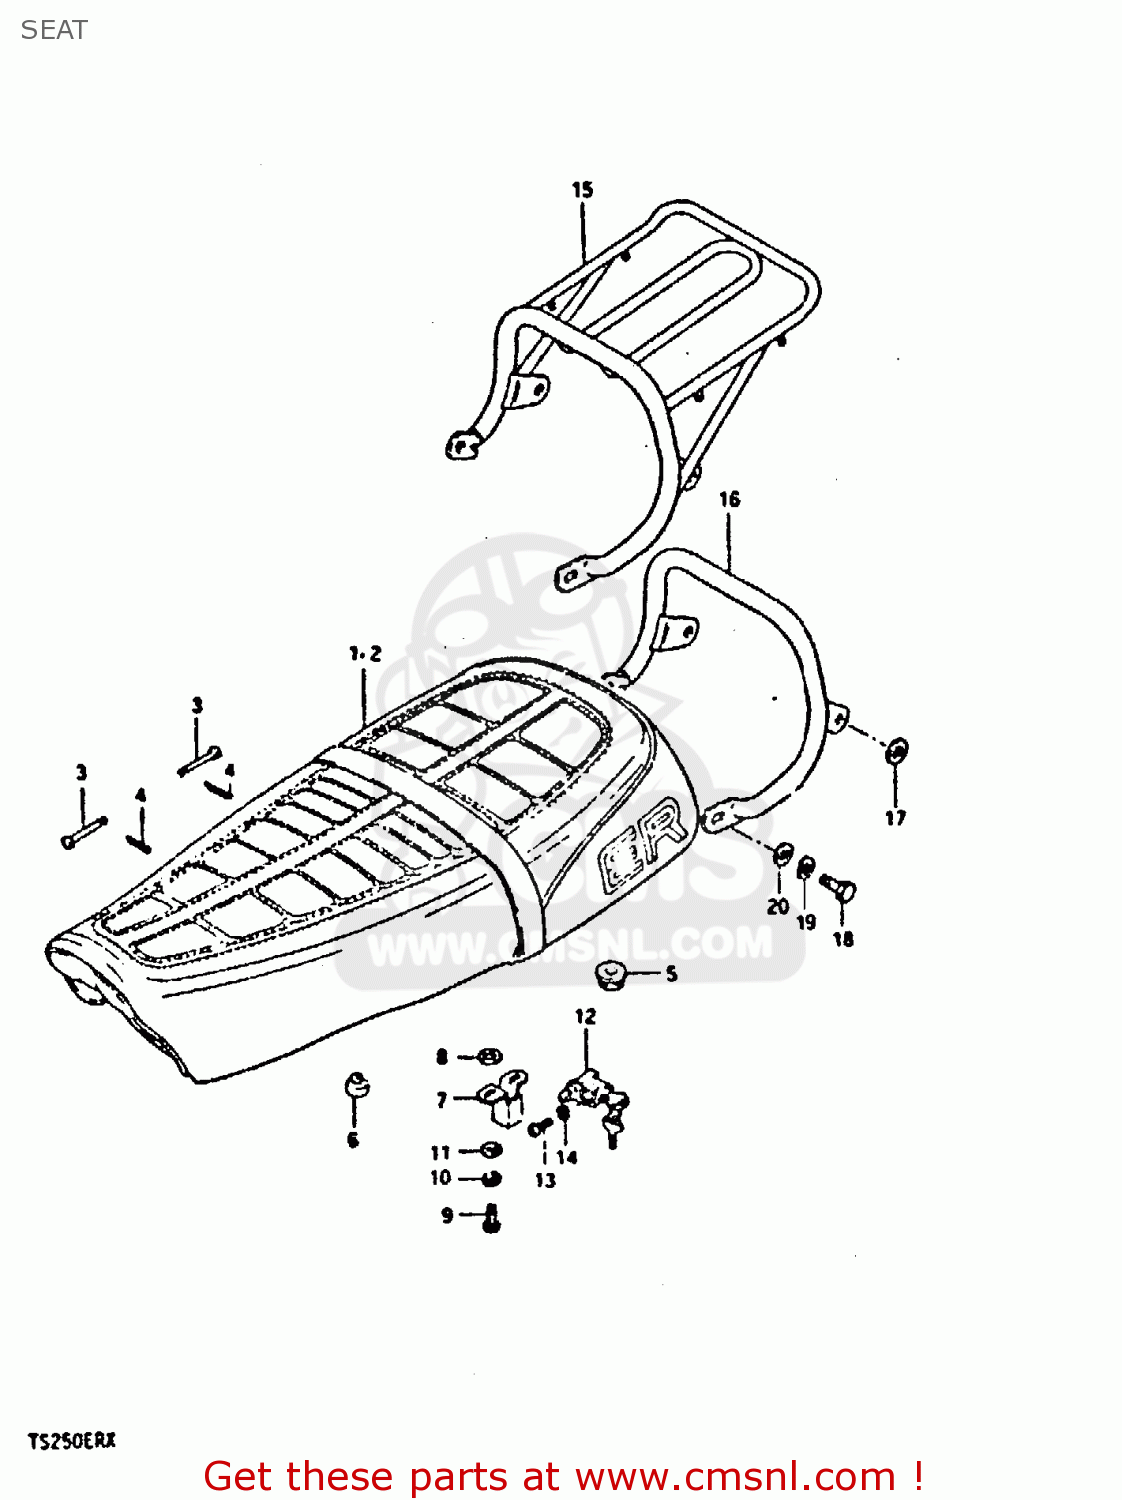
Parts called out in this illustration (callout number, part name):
1	SEAT ASSY
3	PIN
4	PIN
5	CUSHION
6	CUSHION(11.5X22X20)
7	PLATE,CLAMP GUIDE
8	WASHER(8.5X18X1)
9	SCREW 6X12
10	LOCK WASHER
11	WASHER
12	LOCK ASSY,SEAT
13	SCREW
14	LOCK WASHER
15	CARRIER
